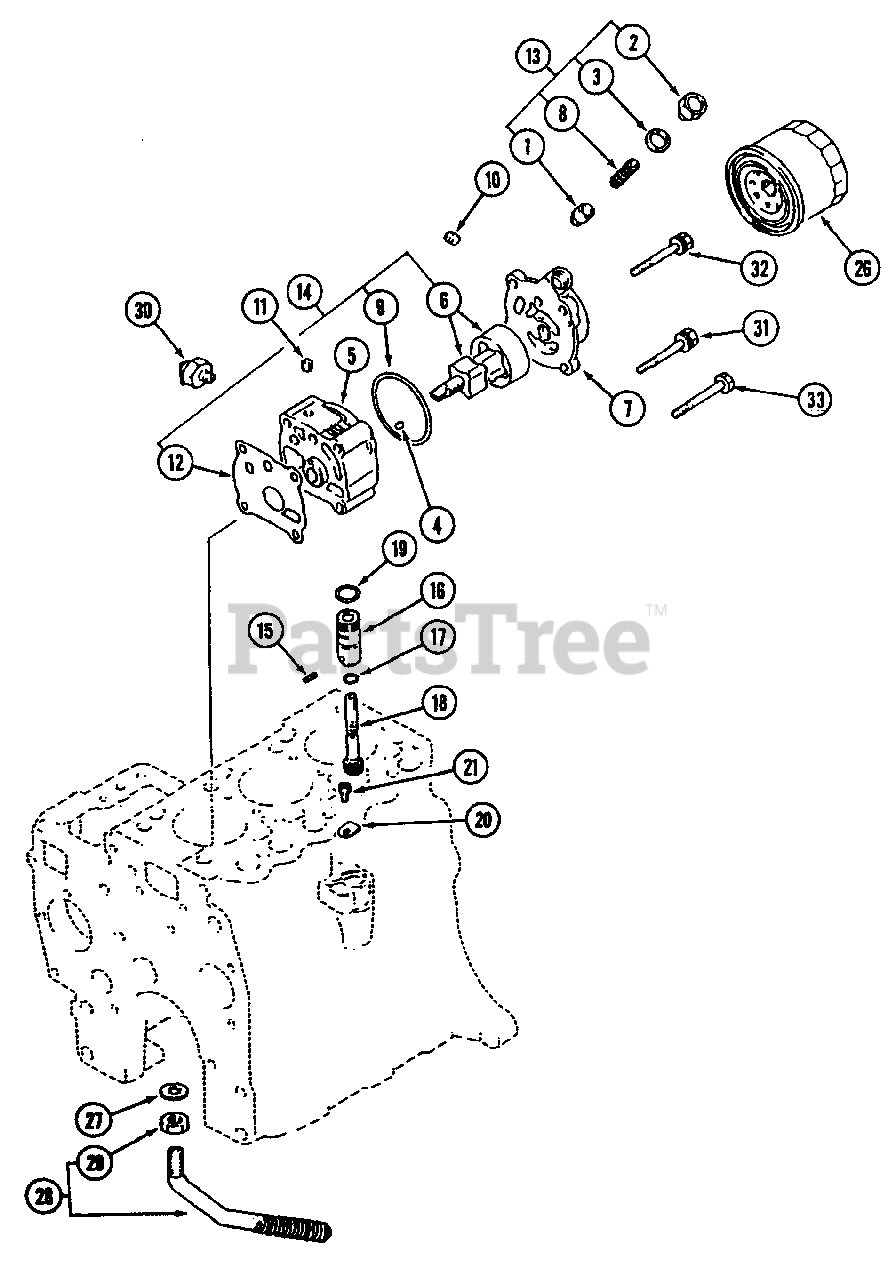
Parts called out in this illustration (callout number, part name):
1	Plunger, Relief
3	Gasket, Oil Drain Plug
4	Pin, Dowel
5	Body, Oil Pump
6	Rotor Ass'y., Oil Pump
7	Cover, Oil Pump
8	Spring, Relief
12	Gasket, Oil Pump Body
13	Service Kit, Relief Valve
14	Service Kit, Rotor
15	Pin, Spring
16	Sleeve, Speedmeter Gear
18	Gear, Speedmeter Driven
19	O-Ring
20	Plate, Locking
21	Bolt, W/Washer
26	Filter Ass'y., Oil
28	Screen Ass'y., Oil
30	Switch Ass'y., Oil Pressure
31	Bolt, Washer Ass'y.
32	Bolt, Washer Ass'y.
